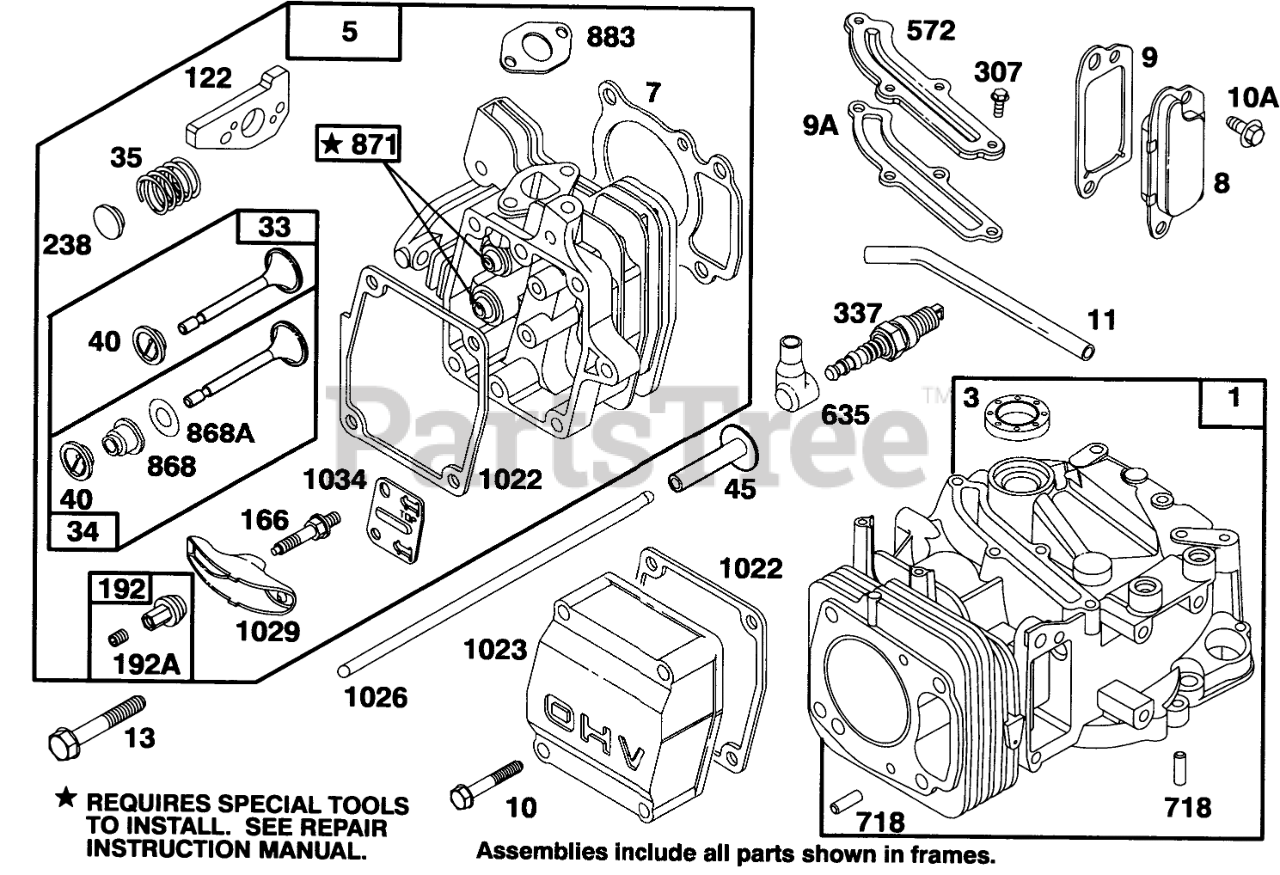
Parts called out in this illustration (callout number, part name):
1	CYLINDER ASSEMBLY
3	SEAL - OIL
5	CYLINDER HEAD
7	CYLINDER HEAD GASKET
8	BREATHER ASM
9	BREATHER GASKET
9A	GASKET-BREATHER
10	HEX HEAD SCREW
10A	HEX HEAD SCREW
11	BREATHER TUBE
13	CYLINDER HEAD SCREW
33	EXHAUST VALVE
34	INTAKE VALVE
35	VALVE SPRING
40	SPRING RETAINER
45	VALVE TAPPET
122	ADAPTER ASSEMBLY
166	ROCKER ARM STUD
192	NUT - HEX SPECIAL
192A	Screw-Set
238	VALVE CAP
307	SCREW - SEM
337	PLUG-SPARK
572	BAFFLE - CYCLINDER
635	SPARK PLUG ELBOW
718	DOWEL - SLEEVE
868	SealAssy-Valve
868A	Seal-Valve
871	Bushing-Guide
883	EXHAUST GASKET
1022	ROCKER COVER GASKET
1023	Cover-Valve
1026	PUSH ROD
1029	ROCKER ARM
1034	PUSH ROD GUIDE
